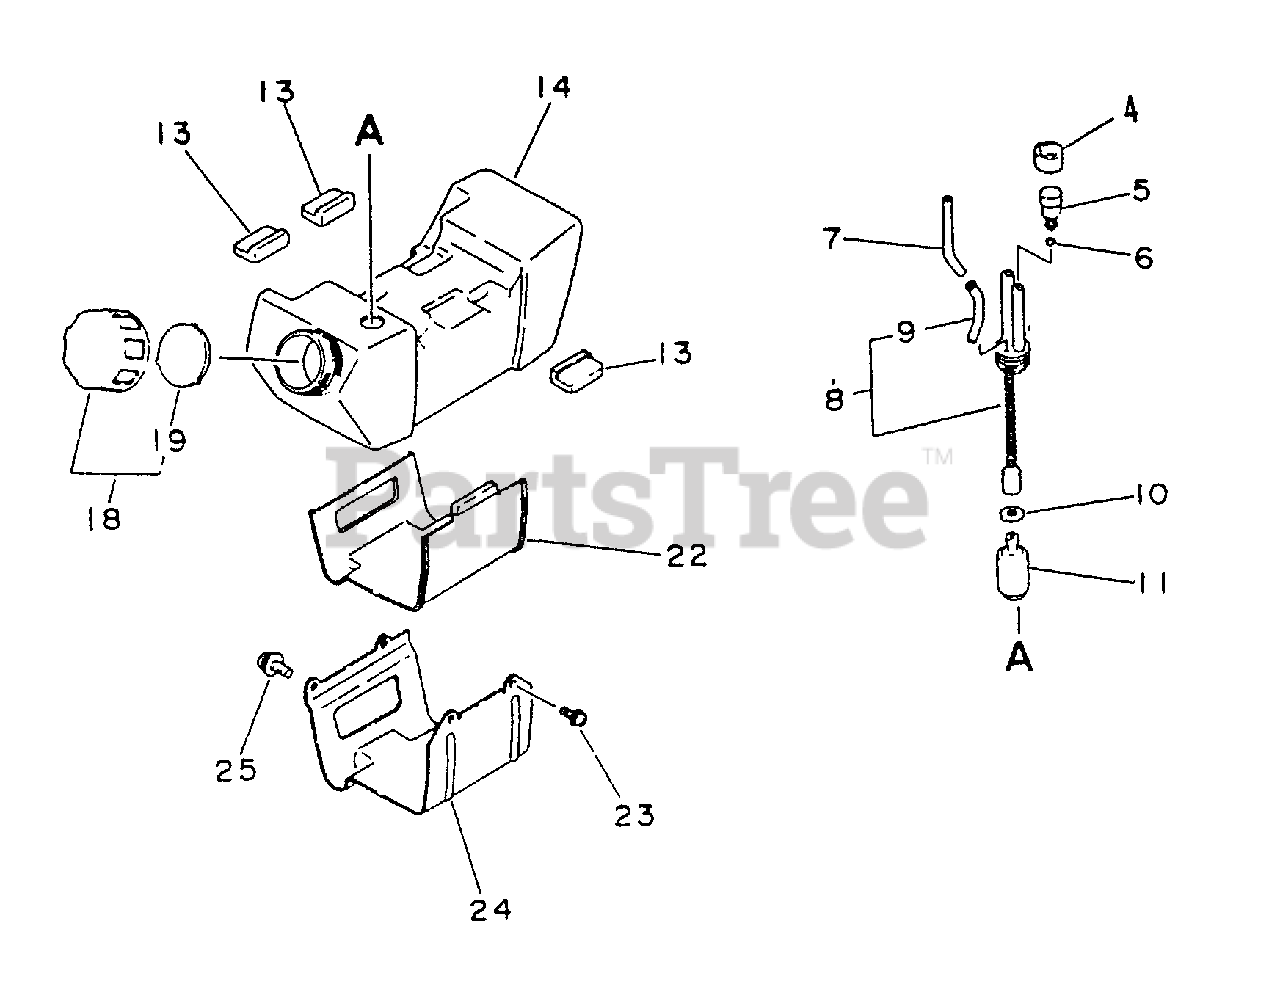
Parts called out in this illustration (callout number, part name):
4	COVER, VENT
5	VENT, FUEL TANK
6	CLIP - 5.5
7	PIPE - 3X6X50 -- CLEAR
8	FUEL SYSTEM KIT
9	CONNECTOR, PIPE
10	WASHER - 5
11	FILTER, FUEL
13	CUSHION, FUEL TANK
14	TANK, FUEL
18	CAP ASSY
19	GASKET, CAP
23	SCREW - 4X10
24	BRACKET, FUEL TANK
25	SCREW - 5X12
